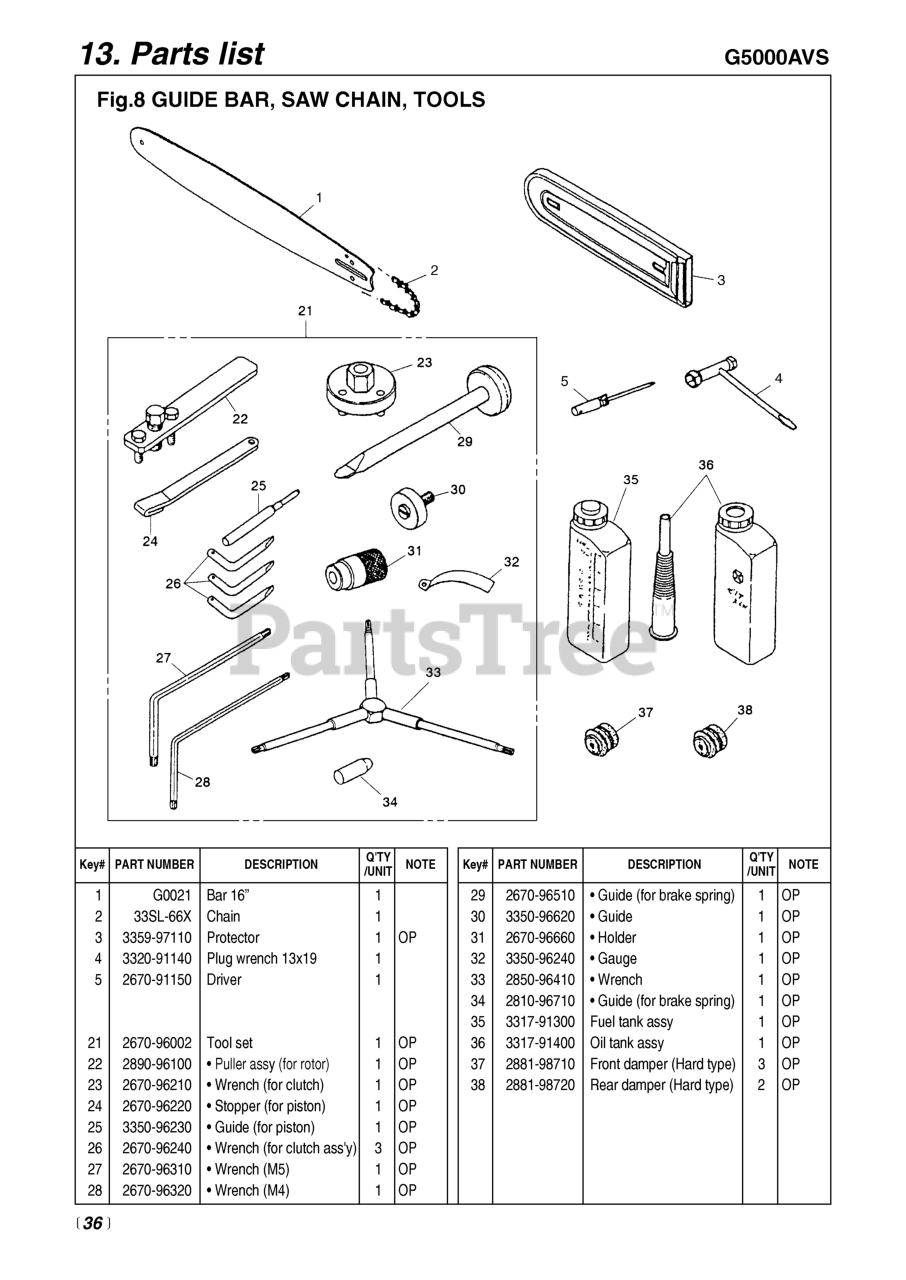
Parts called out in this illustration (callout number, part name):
1	BAR 16
2	CHAIN
4	WRENCH, PLUG
5	SCREWDRIVER
21	TOOL SET
22	PULLER ASSY
23	WRENCH (TOOL)
24	STOPPER (TOOL)
25	GUIDE (TOOL)
26	WRENCH (TOOL)
27	WRENCH (TOOL)
28	WRENCH (TOOL)
29	GUIDE (TOOL)
30	GUIDE (TOOL)
31	HOLDER (TOOL)
32	GUAGE, AIR GAP (TOOL)
33	WRENCH (RPLS. 2670-96410)
34	GUIDE (TOOL)
35	FUEL TANK ASSEMBLY
36	OIL TANK ASSEMBLY
37	FRONT DAMPER (HARD TYPE)
38	REAR DAMPER (HARD TYPE)
